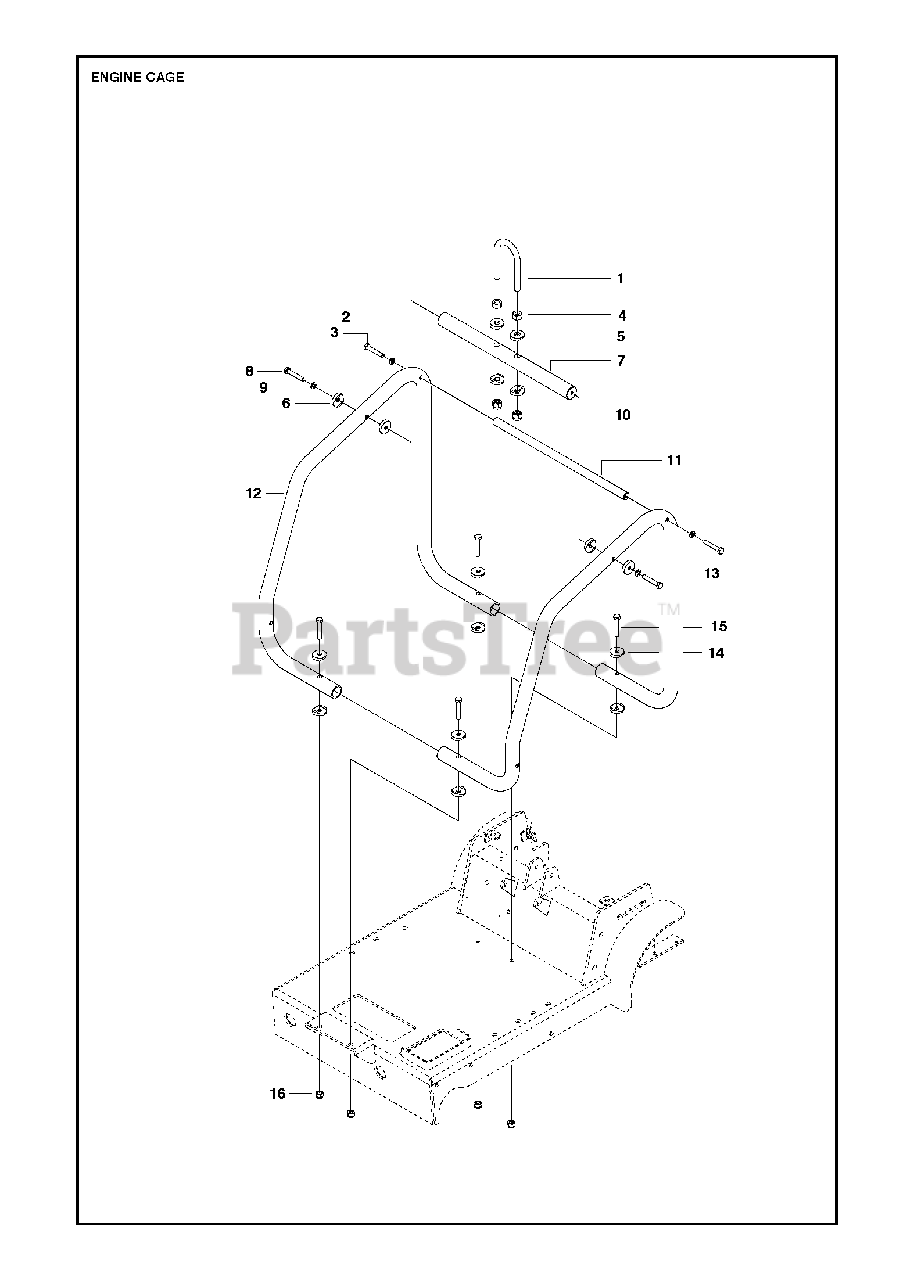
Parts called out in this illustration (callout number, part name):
2	SPRING WASHER
9	SPRING WASHER
12	ENGINE COVERFS520, FS524
13	ENGINE COVERFS520, FS524
16	HEXAGON LOCKING NUT
